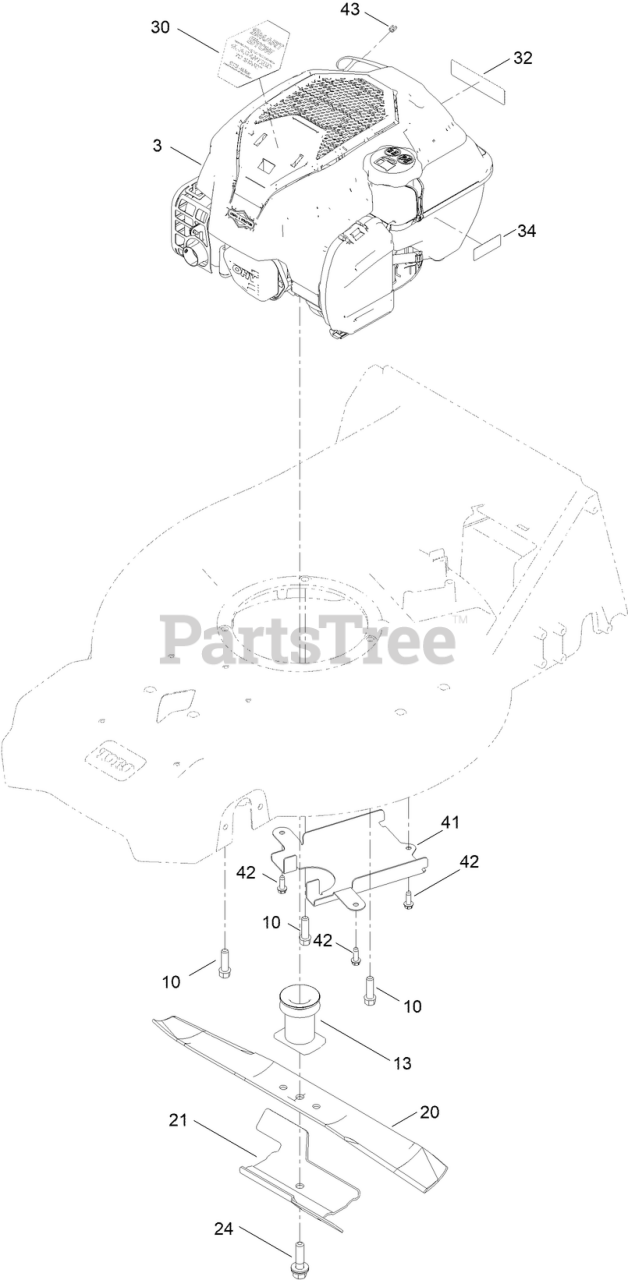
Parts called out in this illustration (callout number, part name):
10	SCREW-TAPTITE
13	DRIVER-BLADE
20	BLADE-21IN, RECYCLING
21	ACCELERATOR-BLADE
24	BOLT-BLADE
30	DECAL-BRIGGS 725 EXI SS
32	DECAL-SHROUD
34	DECAL-LEVEL, FUEL
41	COVER-BELT, BOTTOM
42	SCREW-HWHTF
43	STOP-ROPE
